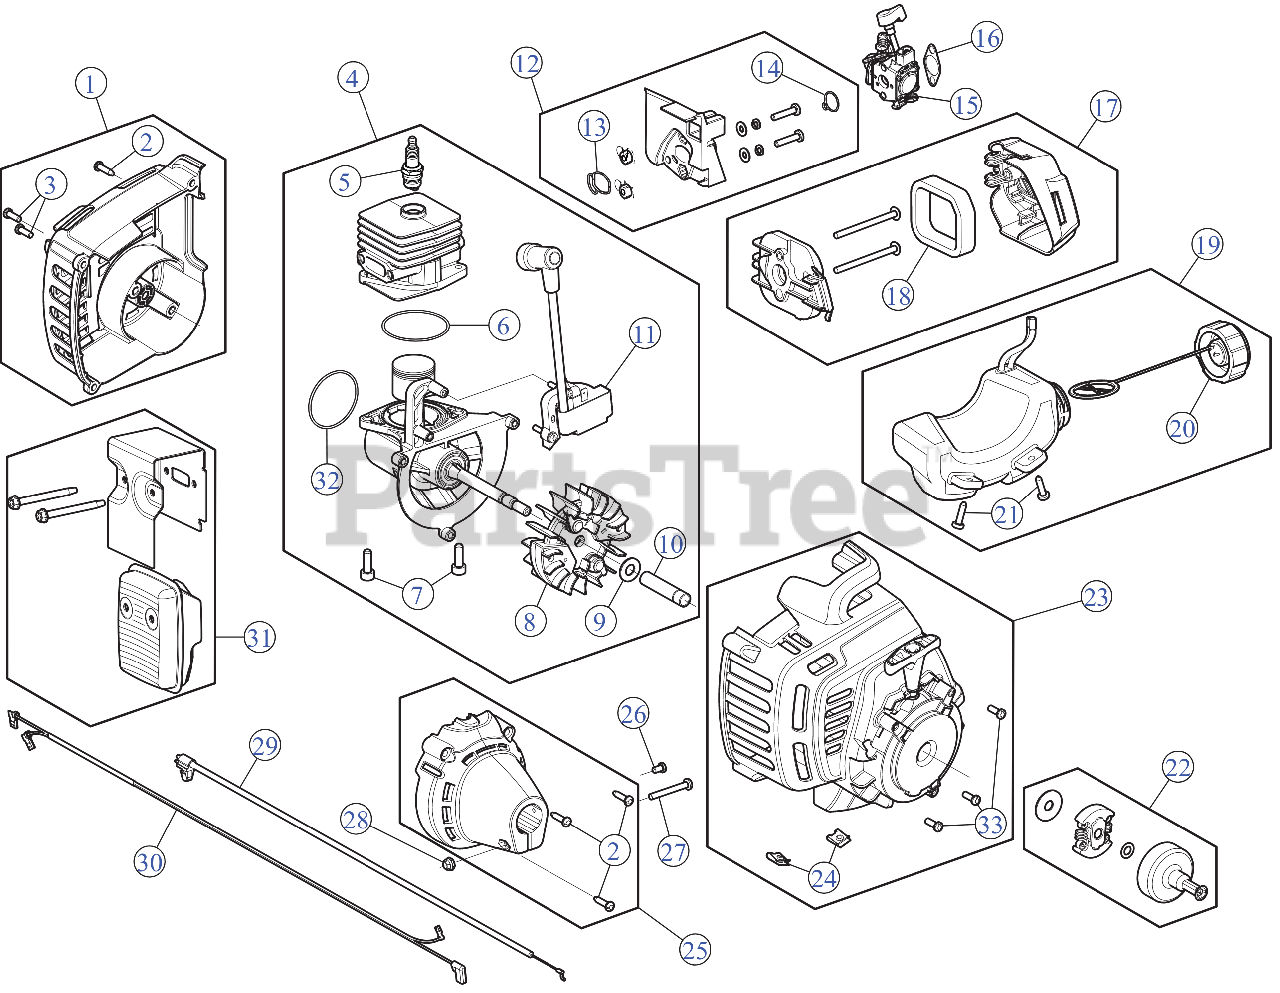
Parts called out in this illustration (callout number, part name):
1	COVER ASSEMBLY
2	SCREW, #8-16X.750 PH
3	SCREW:10-32X.562:#8P
4	SHORT BLOCK
5	SPARK PLUG
6	O-RING
7	SCREW, 1/4-20 x .75
8	FLYWHEEL ASSEMBLY
9	BELL WASHER
10	SPACER
11	MODULE 27CC DIG
12	INTAKE ASSEMBLY
13	O-RING
14	O-RING
15	CARBURETOR
16	GASKET CARB
17	AIRCLEANER COVER ASSEMBLY
18	AIR FLITER
19	FUEL TANK ASSEMBLY
20	FUEL CAP ASSEMBLY
21	SCREW:10-6 x .75
22	SMALL CLUTCH ASSEMBLY W/SMALL DRUM
23	STARTER HOUSING ASSEMBLY
24	NUT, TINNERMAN U-T
25	CLUTCH COVER
26	SCREW, 8-32 x .312 P
27	SCREW
28	HEX NUT
29	THROTTLE CABLE
30	LEAD WIRES
31	MUFFLER ASSEMBLY
32	O-RING
33	SCREW:10-32X.562:#8P
